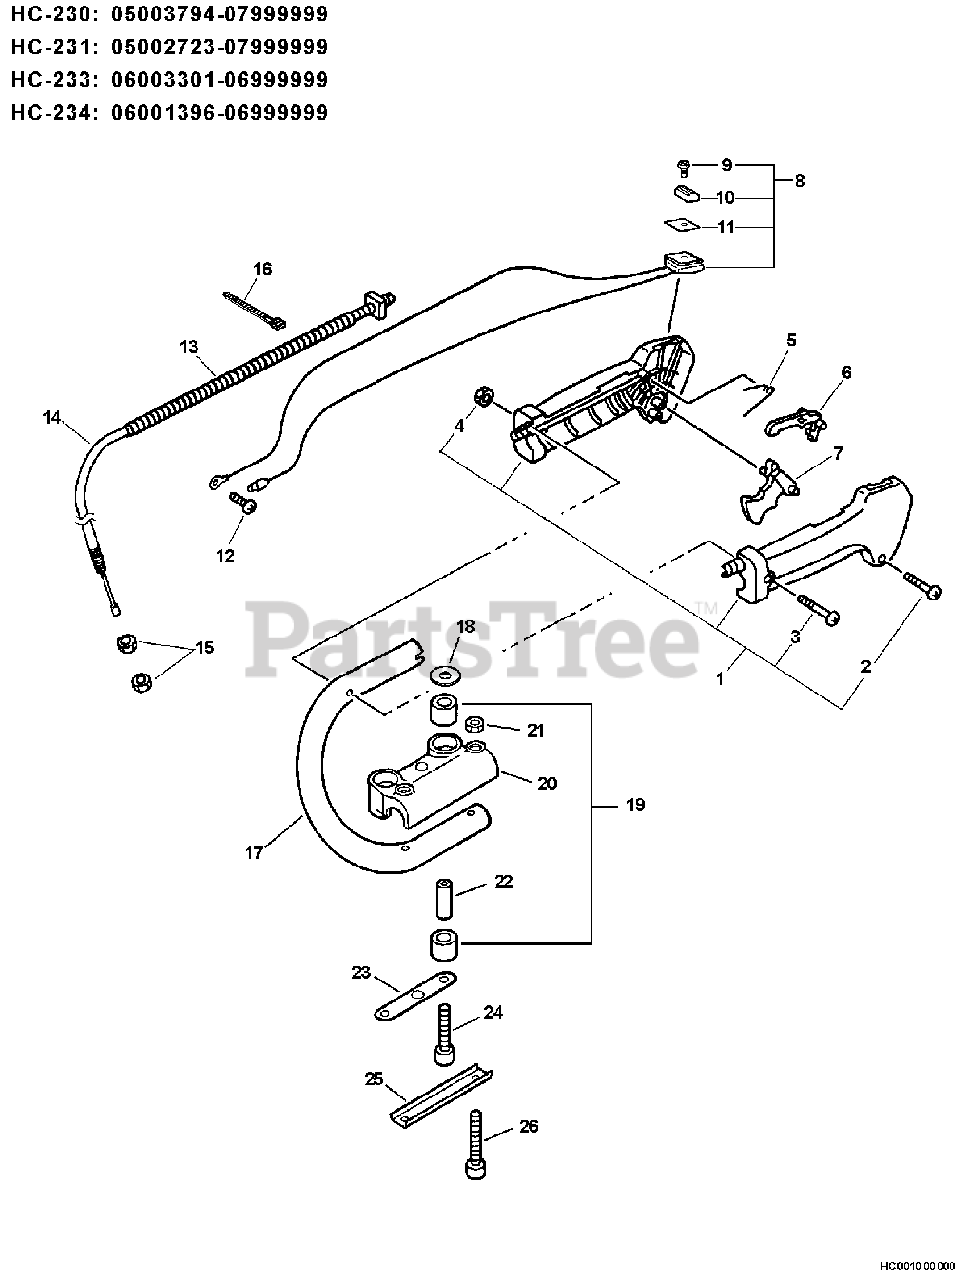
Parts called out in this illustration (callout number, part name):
1	CONTROL HANDLE KIT
2	SCREW 3×25
3	SCREW 5×30
4	NUT M5
5	SPRING, TORSION
6	LOCKOUT, THROTTLE
7	TRIGGER, THROTTLE
8	SWITCH, ON-OFF
9	SCREW 3×10
10	KNOB, SWITCH - ORANGE
11	LABEL, SWITCH
12	SCREW 5×10
13	TUBE, FLEXIBLE
14	CABLE, THROTTLE
16	STRAP, TIE
17	HANDLE, REAR
18	WASHER 5.5×18×1
20	NUT M5
21	BRACKET, HANDLE - UPPER
22	SPACER
23	PLATE, EYE
24	BOLT 5×45
26	BOLT M5×35
